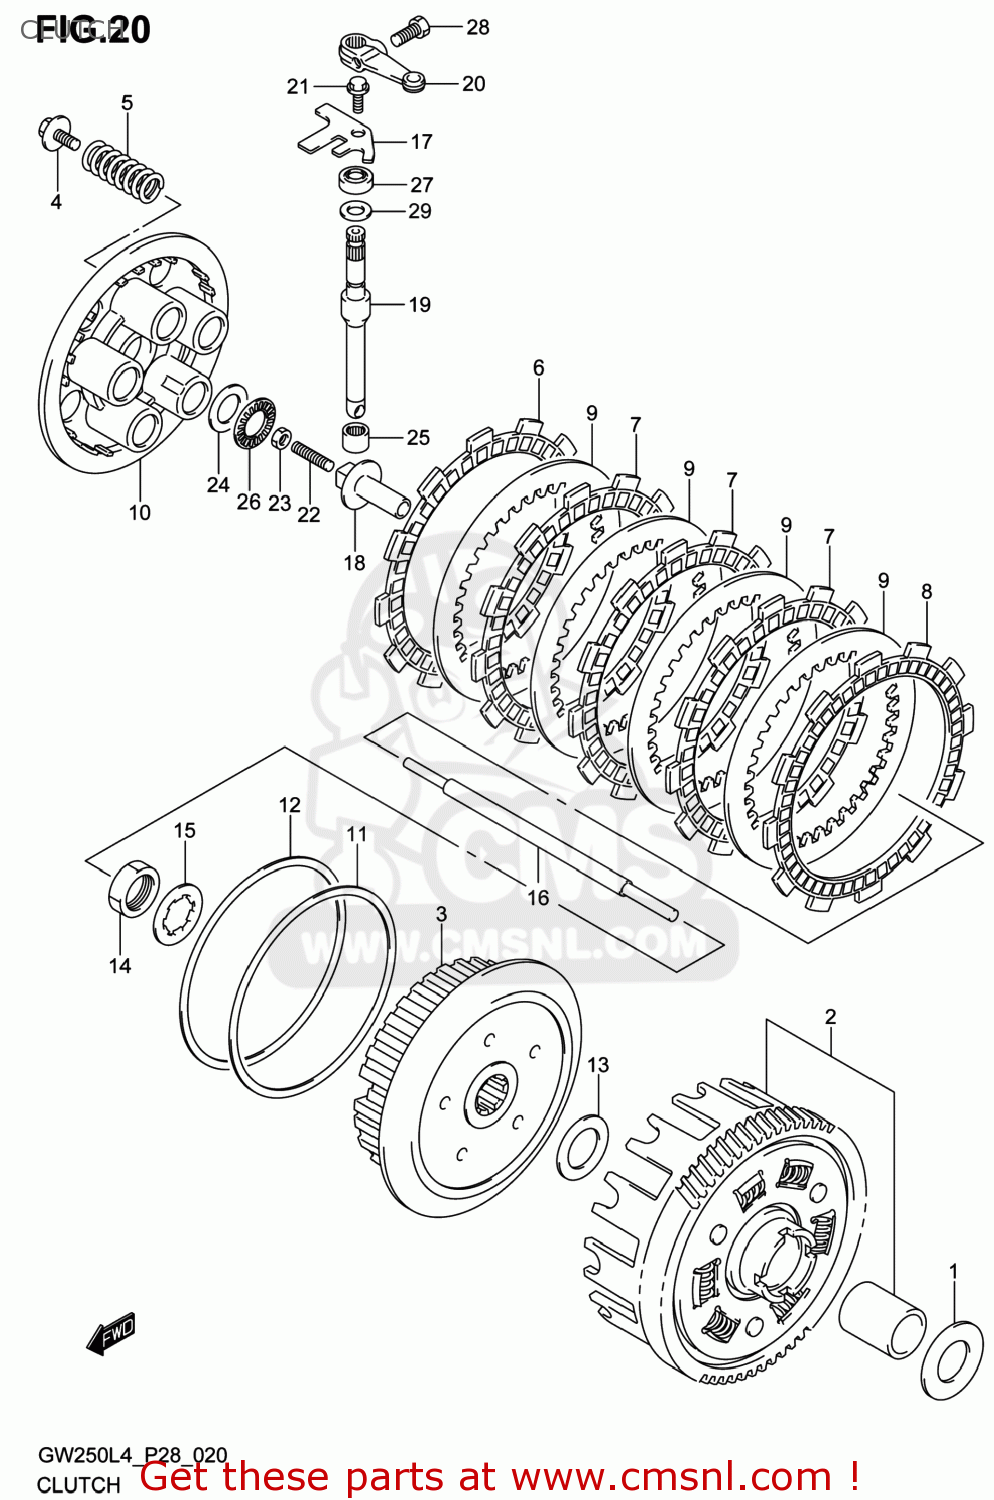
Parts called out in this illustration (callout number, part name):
1	WASHER
2	GEAR ASSY,PRI DRIVEN
3	HUB,CLUTCH SLEEVE
4	BOLT,CLUTCH SPRING
5	SPRING,CLUTCH
6	PLATE,CLUTCH DRIVE NO.1 (NAS)
7	PLATE,CLUTCH DRIVE NO.2 (NAS)
8	PLATE,CLUTCH DRIVE NO.3 (NAS)
9	PLATE,CLUTCH DRIVEN (NAS)
10	DISC,CLUTCH PRESSURE
11	SEAT,WAVE WASHER
12	WASHER,CLUTCH SLEEVE HUB WAVE
13	WASHER,THRUST
14	NUT
15	WASHER,LOCK
16	ROD,CLUTCH PUSH
17	RETAINER,CL RLSE OIL SEAL
18	PIECE,CLUTCH PUSH
19	CAMSHAFT,CLUTCH RELEASE
20	ARM,CLUTCH RELEASE
21	BOLT(6X12)
22	SCREW(6X25)
23	NUT
24	WASHER(15.5X28X1)
25	BEARING,10X14X10
26	BEARING(15X28X2)
27	SEAL,OIL(10X17X5)
28	BOLT
29	WASHER(12.5X17X1)
